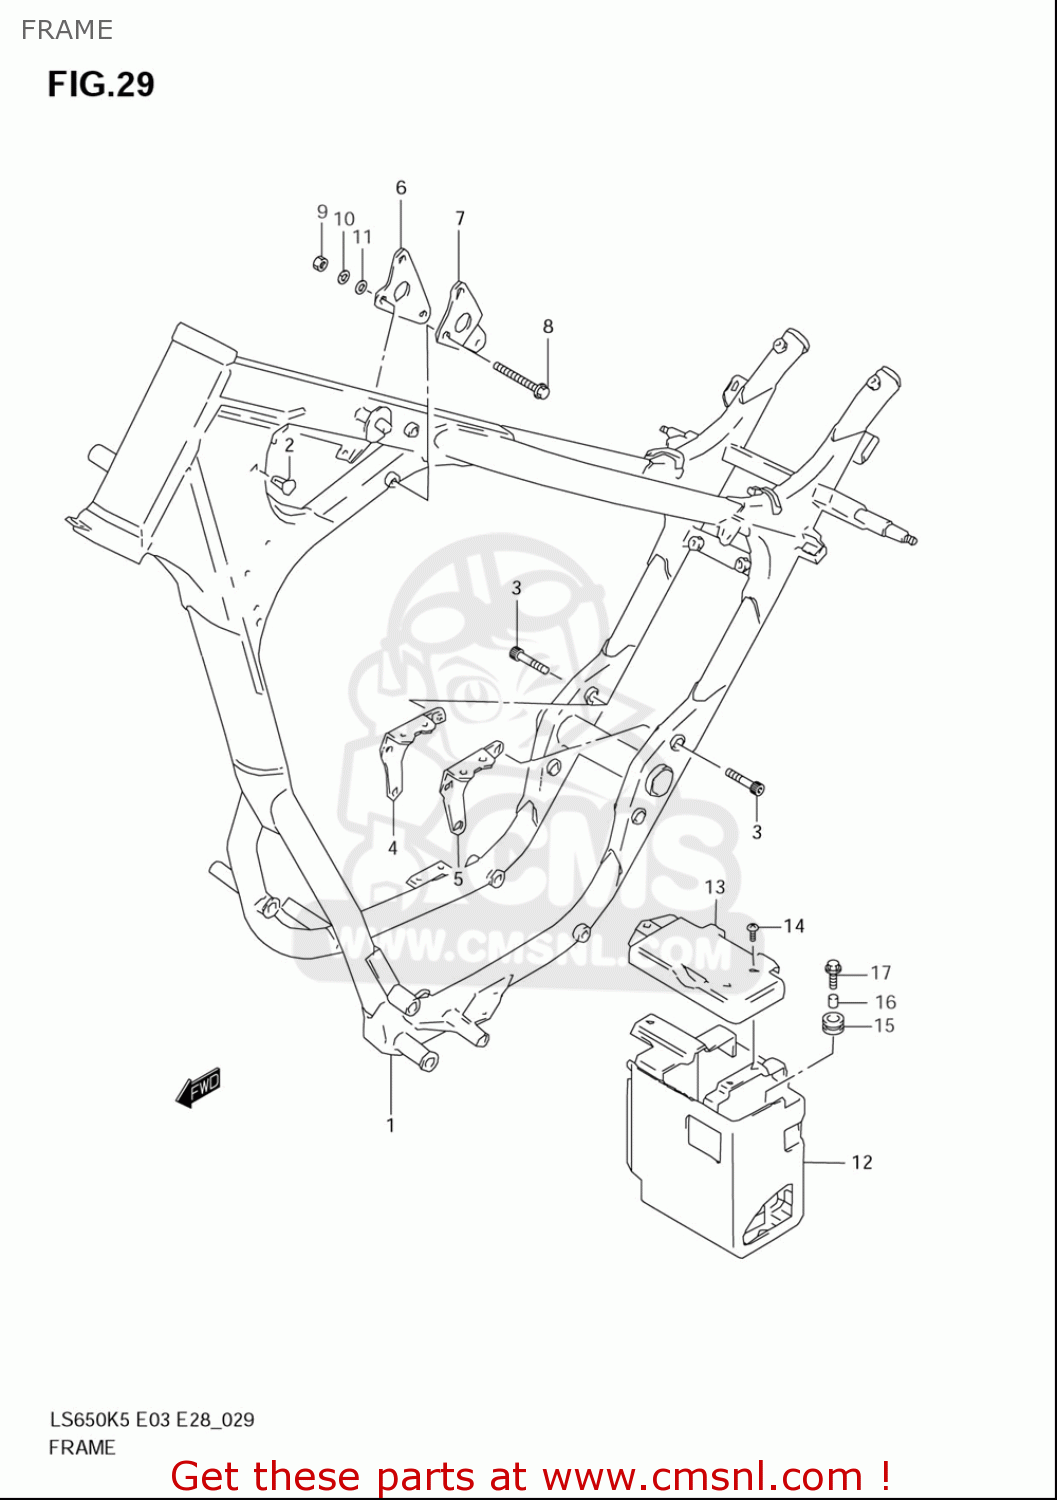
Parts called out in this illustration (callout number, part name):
1	FRAME(BLACK)
3	BOLT(8X40)
5	PLATE,ENGINE MOUNT NO.4,L
6	PLATE,ENGINE MOUNT NO.5,R
7	PLATE,ENGINE MOUNT NO.5,L
9	NUT
10	WASHER,LOCK
11	WASHER
12	HOLDER,BATTERY
13	COVER,BATTERY
14	SCREW
15	CUSHION
16	SPACER(6.5X9X7.2)
17	BOLT(6X20)
